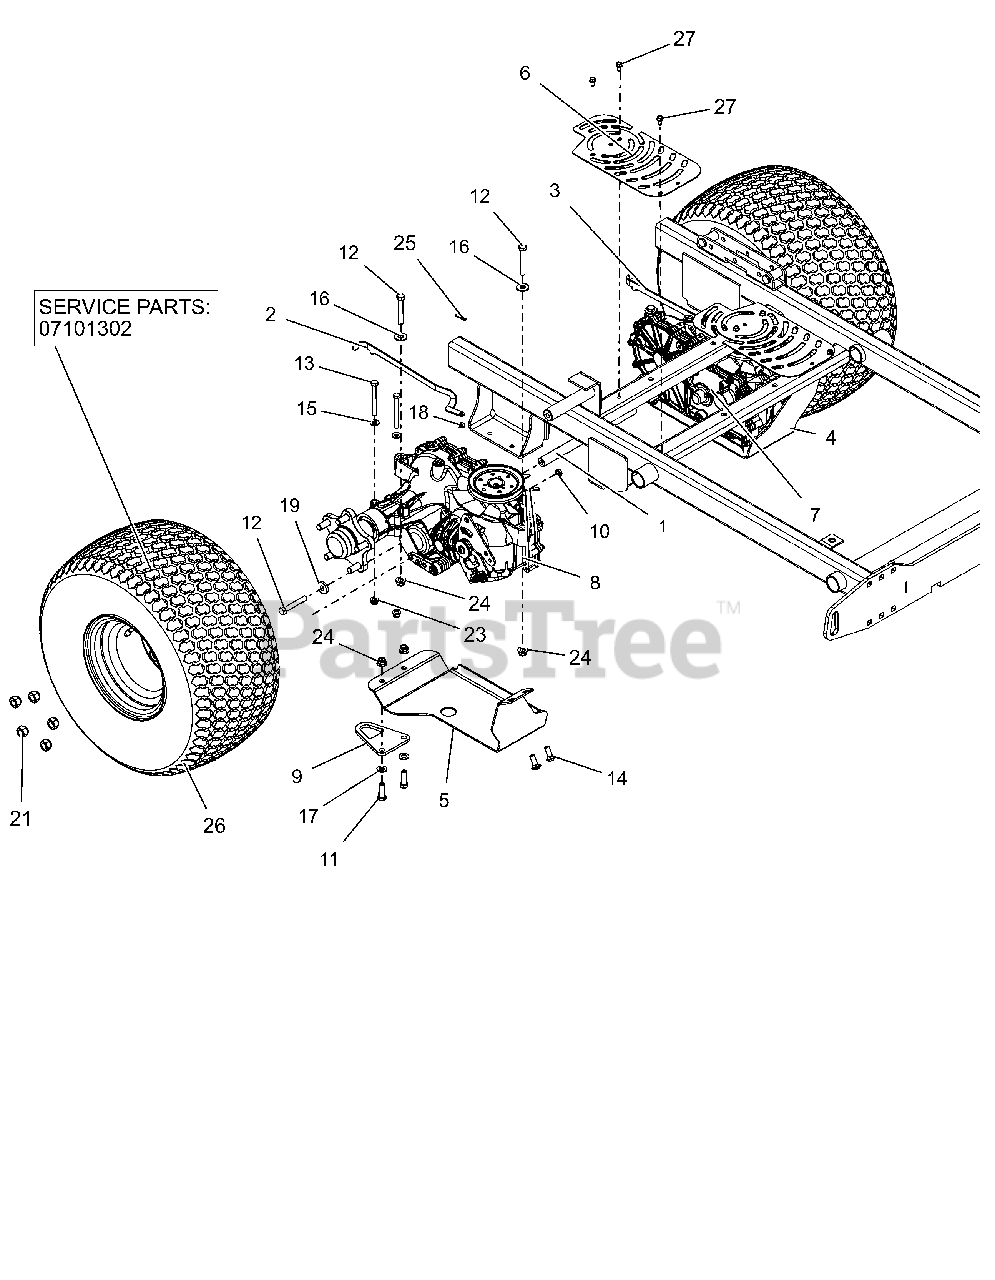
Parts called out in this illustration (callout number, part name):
1	SHAFT, CROSS BRACE
2	BRKT, LH DUMP VALVE
3	BRKT, RH DUMP VALVE
4	PLATE, LH SKID
5	PLATE, RH SKID
6	GUARD, PROSTANCE FAN
7	TRANSAXLE, ZT3400, LH
8	TRANSAXLE, ZT3400, RH
9	BRKT, TIE DOWN
10	@NUT-LK-CTR-JAM .31-18 YWZC
11	@BLT-HEX .38-16X1.25 GR5 YWZC
12	@BLT-HEX .38-16X2.50 GR5 YWZC
13	@BLT-HEX .31-18X3.00 GR5 YWZC
14	@BLT-RDHDSQNK .38-16X1.00 G5YZ
15	@WSHR-FL-STL.312X.734X.065 YWZ
16	@WSHR-FL-STL.438X1.00X.083 YWZ
17	@WSHR-FL-STL.406X.812X.065 YWZ
18	@WSHR-FL-STL.281X.62X.065 YWZC
19	WSHR-FL-STL .406X1.00X.188 YWZ
21	WHEEL NUT .500-20 YZ
23	@NUT-LK-NYL-FLG .31-18 YWZC
24	@NUT-LK-NYL-FLG .38-16 YWZC
25	PIN-HAIR, ENDRIES #25 YWZC
26	ASM, WHL/TIRE 20X10.5-8 RADIAL
26	TIRE, 20 X 10.5-8 4 PLY RADIAL
27	SCR-TAP .25-20X.50 HWH TR YWZ
